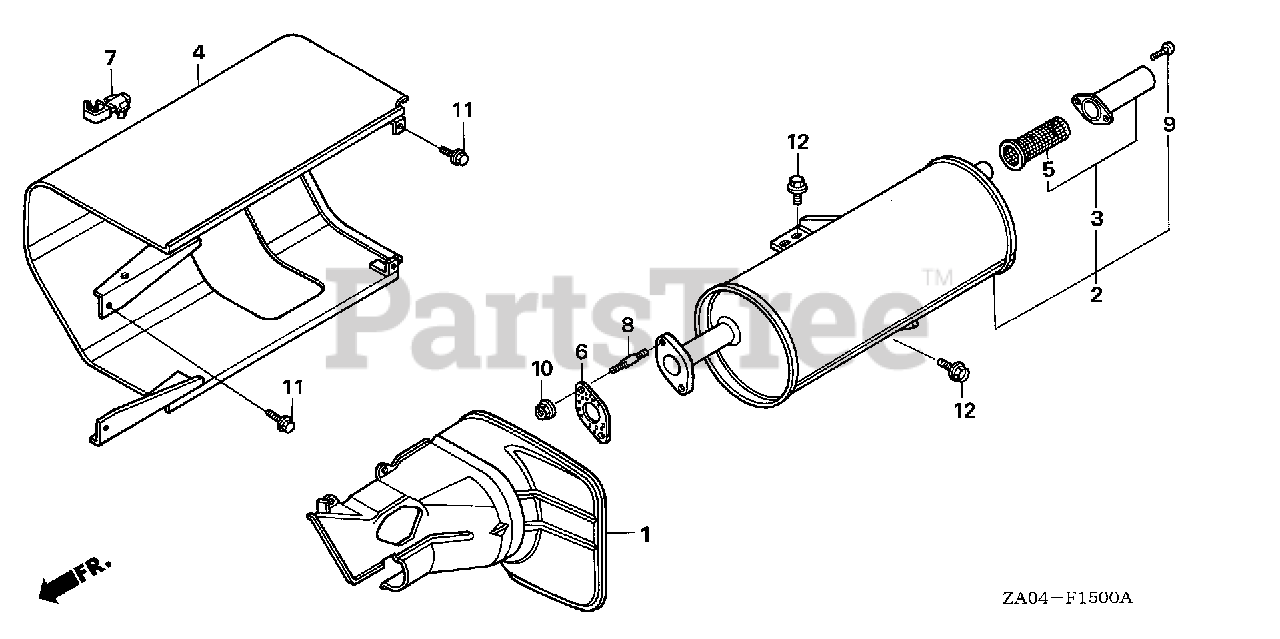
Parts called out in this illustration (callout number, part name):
1	COVER, EX.
2	MUFFLER
3	CAP SET, ARRESTER (NOT AVAILABLE)
4	SEPARATOR, MUFFLER
5	ARRESTER, SPARK
6	GASKET, MUFFLER
7	CLIP, HARNESS (5MM-15MM) (BLACK)
8	BOLT, STUD (8X35)
9	SCREW, PAN (5X8)
10	NUT, FLANGE (8MM)
11	BOLT, FLANGE (6X12) Use up to Engine SN 1543277.
12	BOLT, FLANGE (8X20)
12	BOLT, FLANGE (8X20) Use up to Engine SN 1609606.
